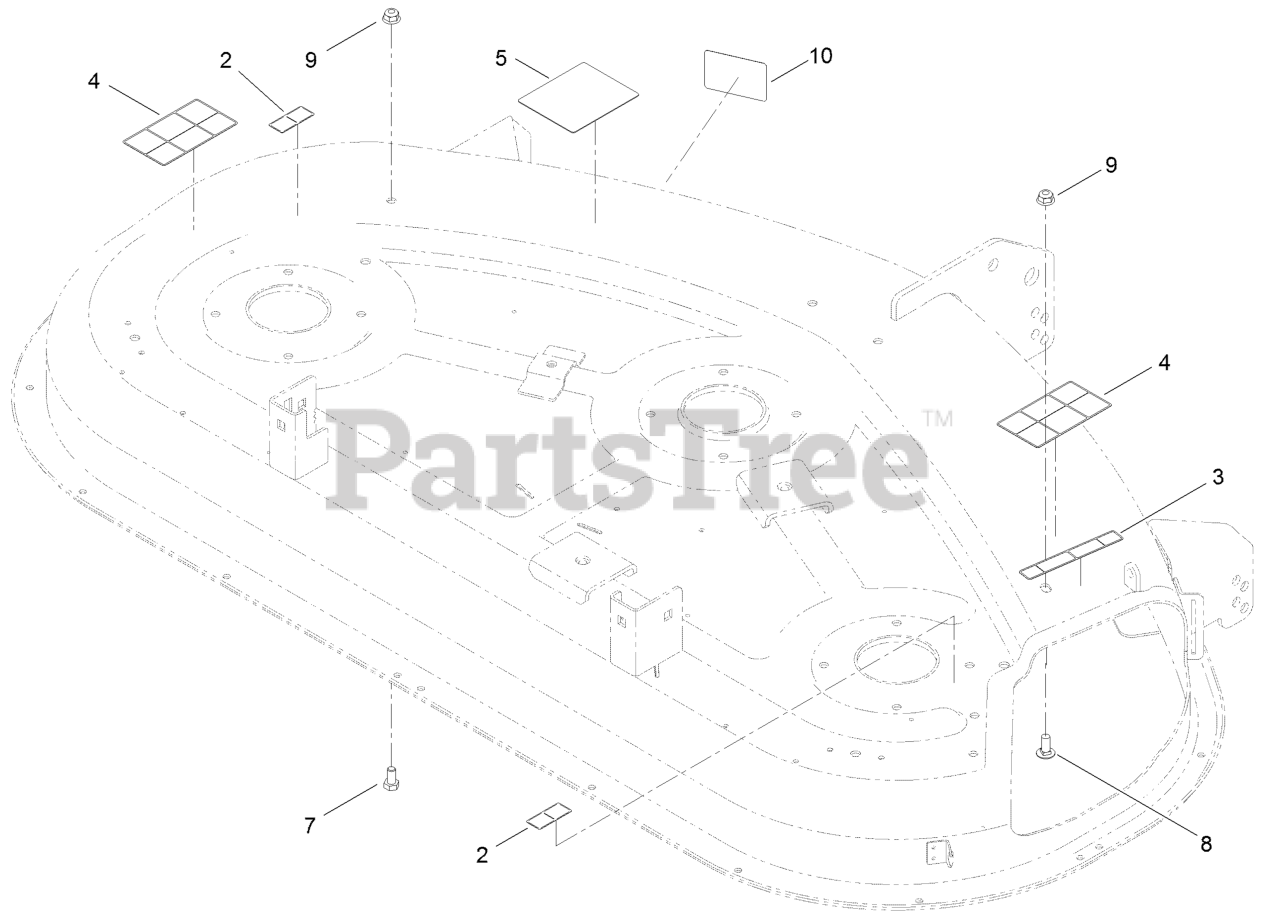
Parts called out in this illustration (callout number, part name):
2	DECAL-DANGER
3	DECAL-DANGER
4	DECAL-DANGER
5	DECAL-ROUTING, BELT
7	SCREW-HH
8	SCREW-CARR
9	NUT-HF, NI
10	DECAL-SCALP, ANTI
